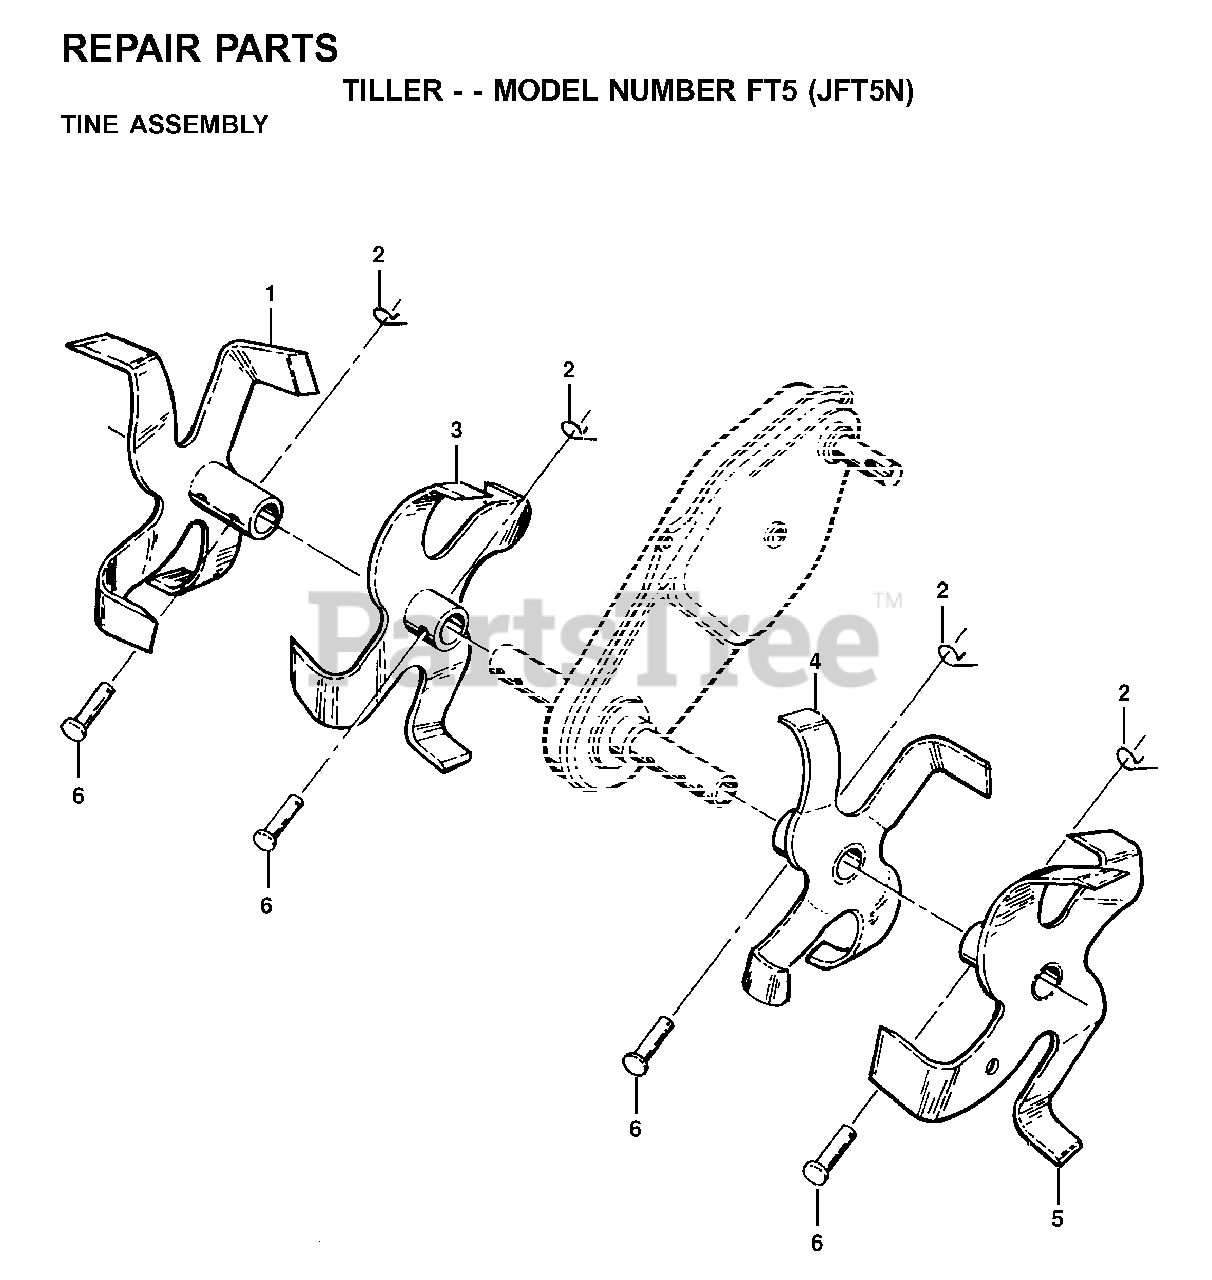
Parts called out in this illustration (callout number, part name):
1	RP TINE
2	SPRING RETAINER
3	RP TINE
4	RP TINE
5	RP TINE
